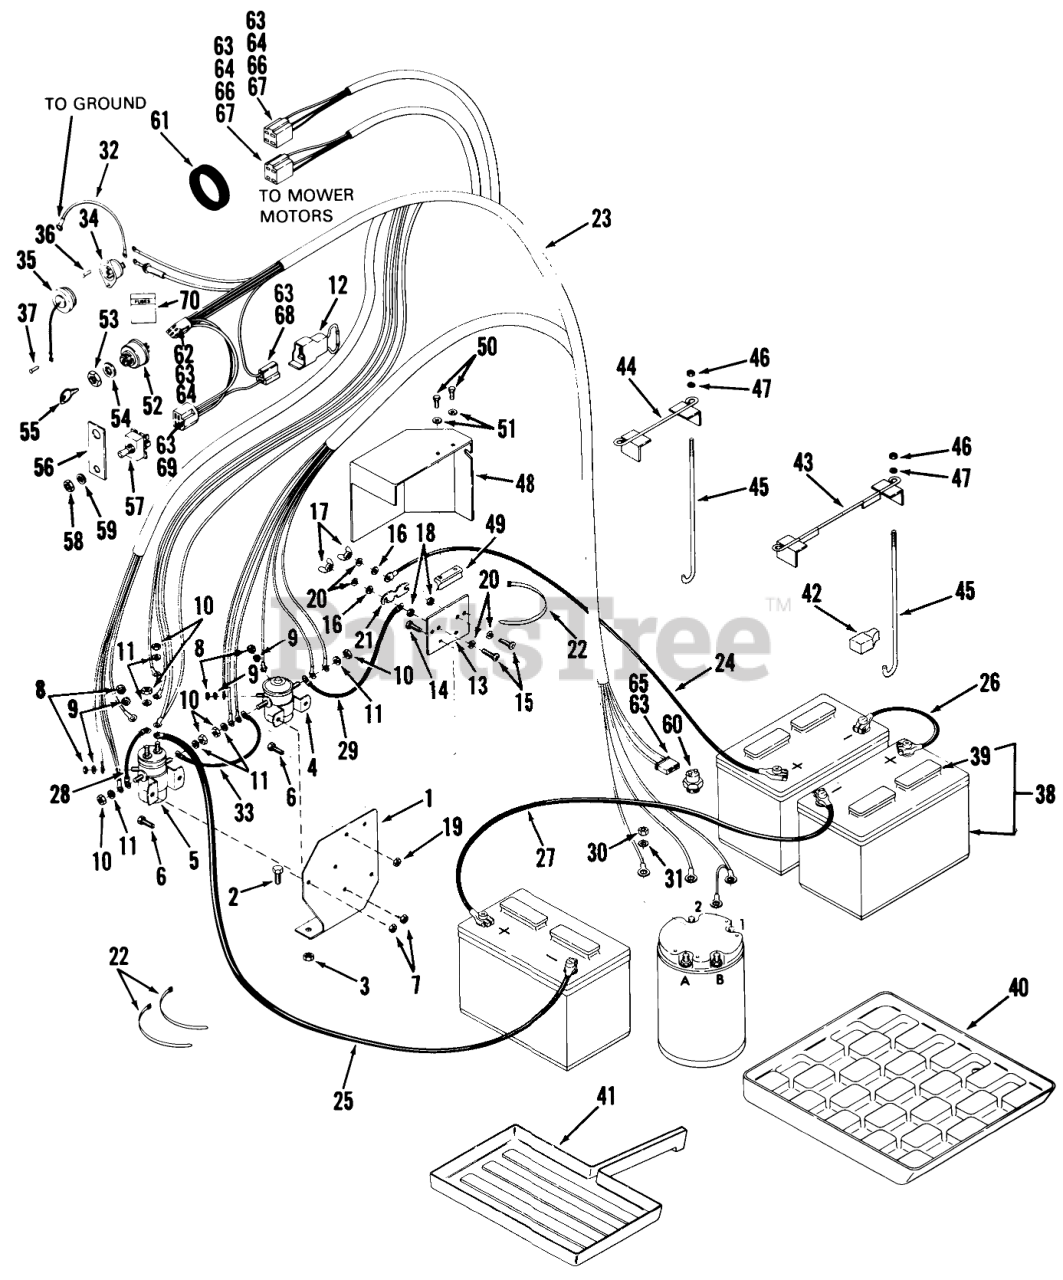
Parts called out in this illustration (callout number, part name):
1	Plate-Component Mounting
2	H H C S
3	Nut
4	Solenoid-Traction Motor
5	PTO Contactor
6	Bolt
7	Nut
8	Nut
9	Lockwasher
10	Nut
11	Lockwasher
12	Diode
13	Bracket-Fuse
14	Bolt
15	Screw 1/4-20 X 3/4 Brass
16	Washer 1/4
17	Wing Nut 1/4-20
18	Nut, 1/4-20
19	Nut
20	Washer
21	Fuse-Main 75 Amp Buss Type WEA
22	PLASTIC TIE
23	Wiring Harness
24	Battery Cable-Bat. Pack Pos.
25	Battery Cable-Bat. Pack Neg
26	Battery Cable Assembly
27	Battery Cable-Long Jumper
28	Wire-Mower Solenoid
29	Wire-Traction Solenoid To Fuse
30	Nut
31	Washer
32	Wire-Charger Conn. To Ground
33	Wire
34	Plug-Charger
35	Cover-Charger Plug
